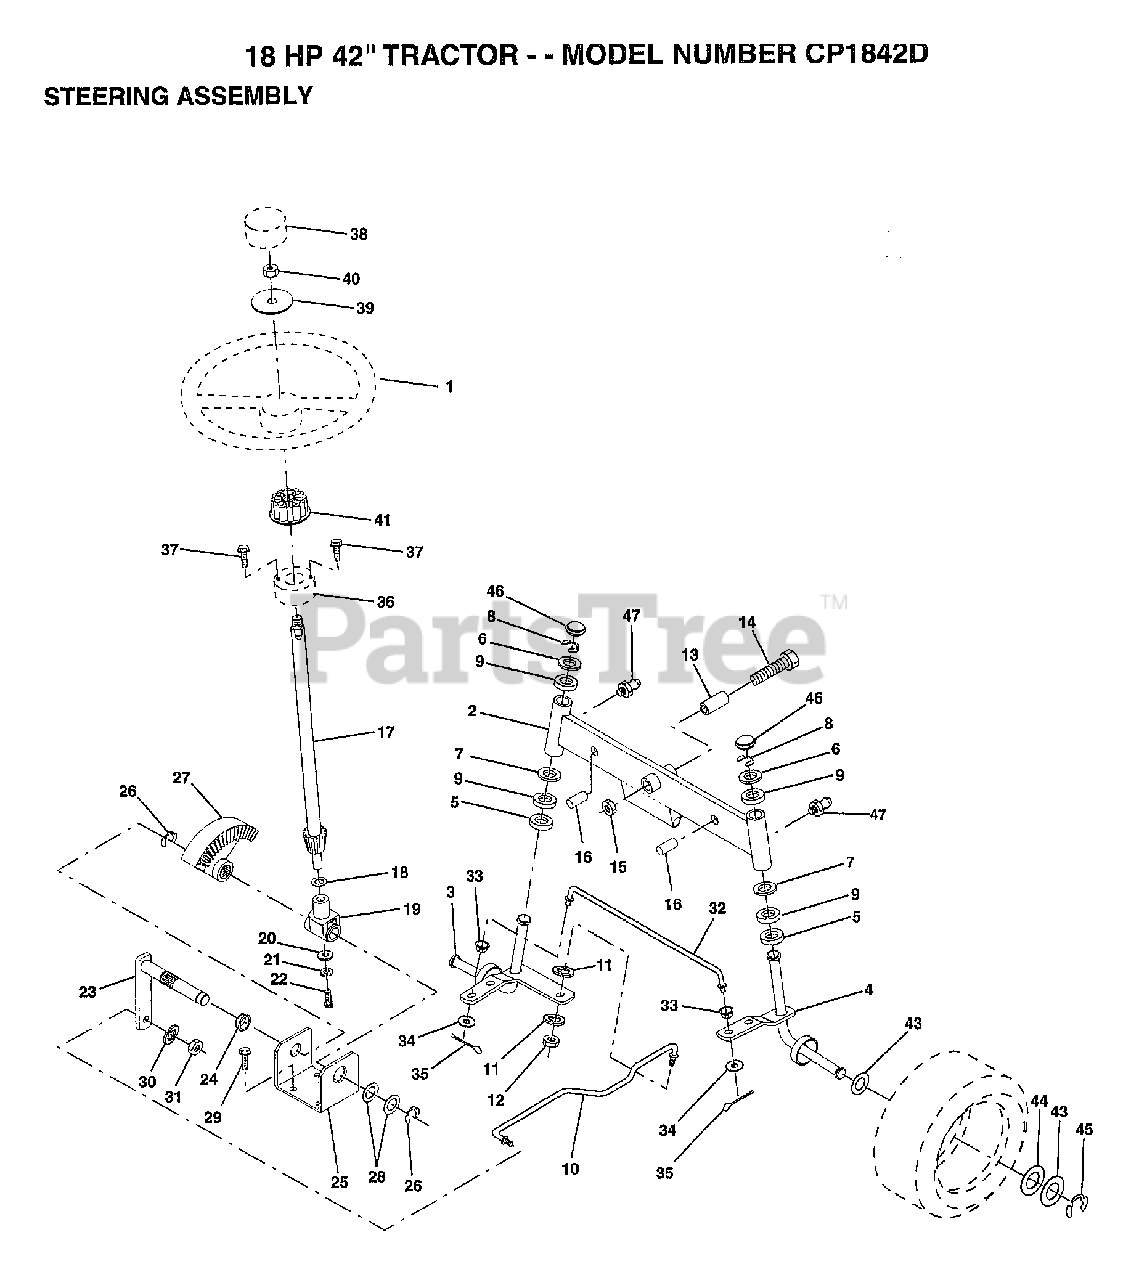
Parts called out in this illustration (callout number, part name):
2	AXLE ASM FRONT
3	SPINDLE LH
4	SPINDLE RH
5	WASHER .T
6	WASHER
7	WASHER
8	RING
9	COL. SRTG. BEAR.
11	LOCKWASHER
13	BEARING
14	BOLT HEX 5/8-11
15	"NUT-LOC,FLANGE LT"
16	AXLE PIN
17	STEERING SHAFT
18	THRUST WASHER
19	SUPPORT.SHAFT
21	LOCKWASHER
22	"SCREW,SPECIAL"
24	NYLINER T
25	"BRKT,STEERING"
26	RING
27	GEAR SECTOR
28	WASHER .T
29	SCREW
30	LOCKWASHER
32	TIE ROD
33	BUSHING.DRAGLINK
34	WASHER
35	COTTER PIN
38	"INSERT,STR WHEEL"
39	WASHER
41	ADAPTER LT
43	WASHER
44	WASHER
45	RING
46	CAP
47	ZERK M
